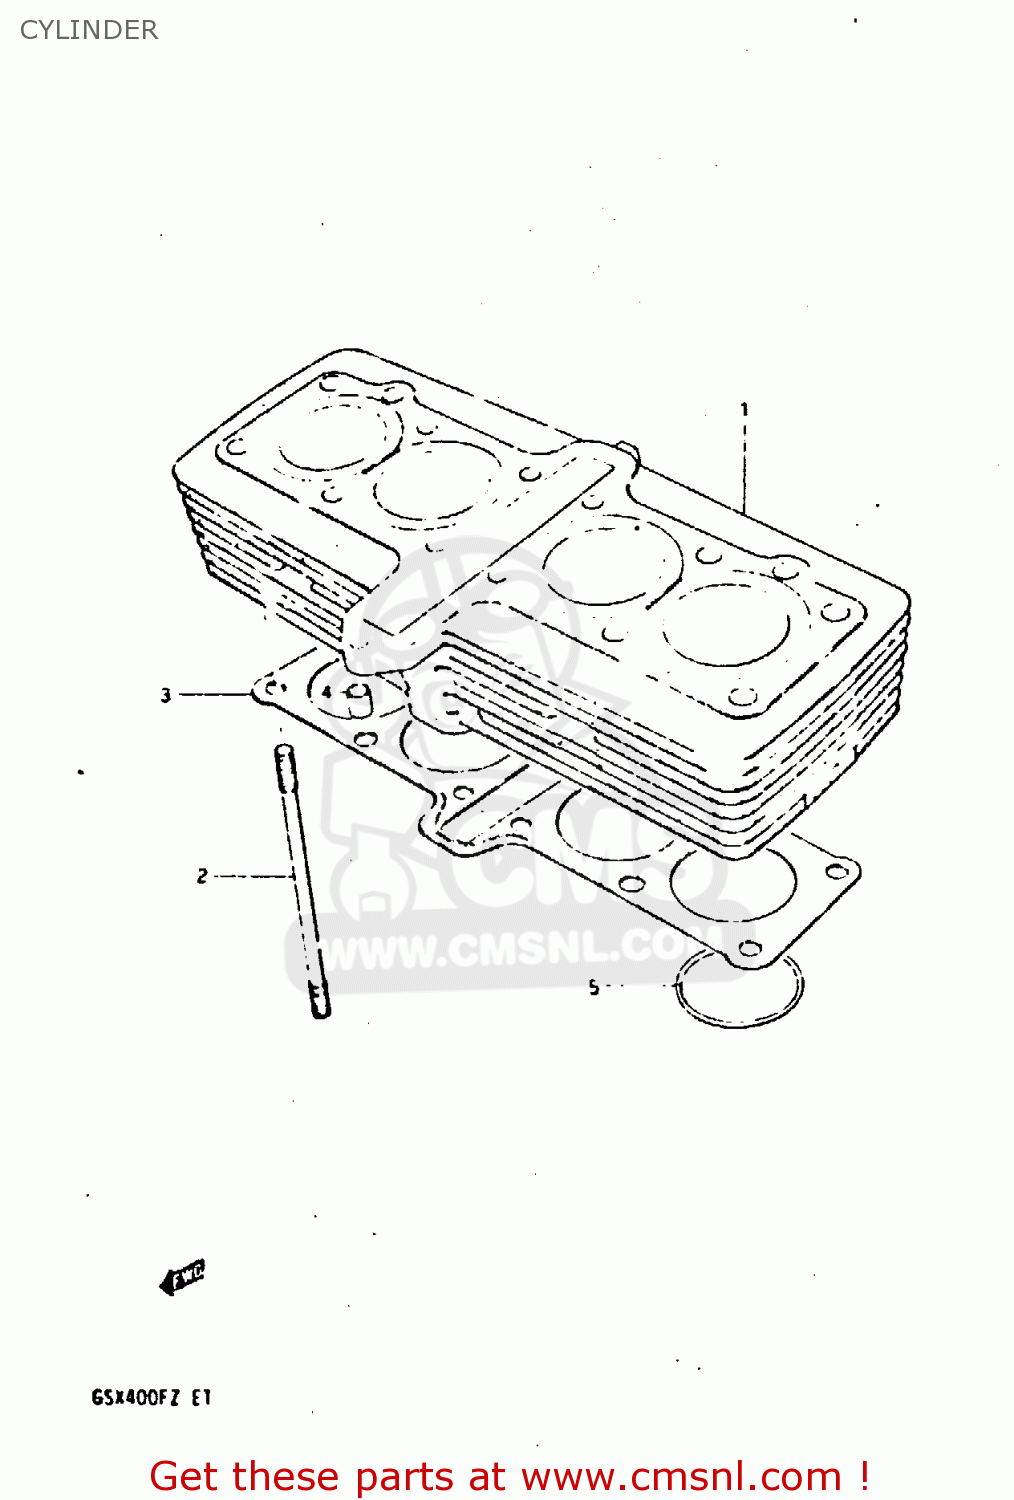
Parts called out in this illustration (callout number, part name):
1	CYLINDER
2	STUD
3	GASKET (T:0.8) (MCA)
4	PIN
5	O-RING (D:2 ID:56.5)
